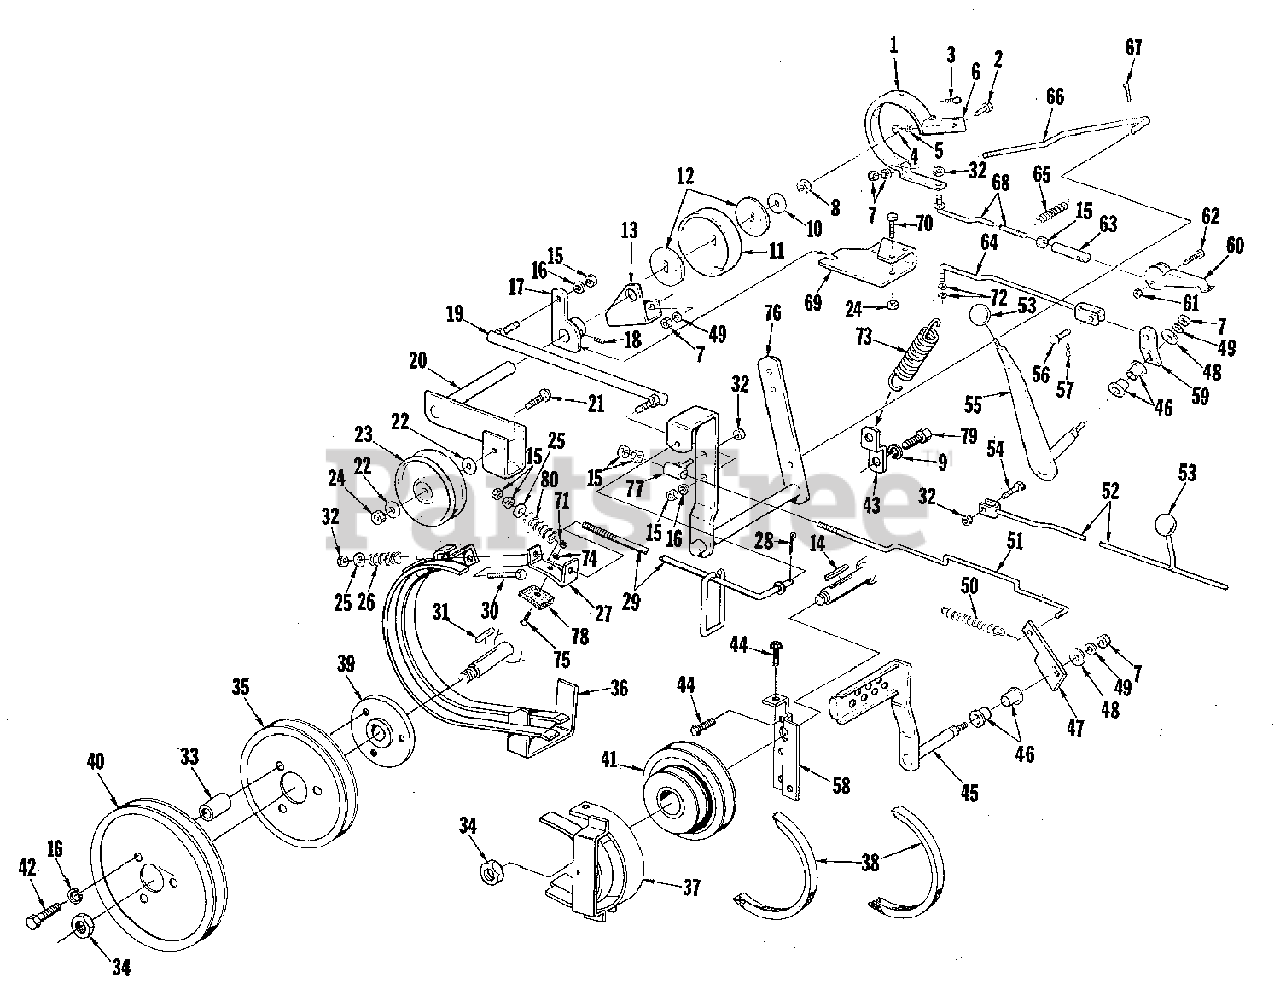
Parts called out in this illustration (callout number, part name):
1	BAND ASSEMBLY, Brake
2	SCREW, Hex Head Cap, 3/8-16 x 1-1/4
3	SCREW, Hex Head Cap, 1/4-20 x 3/4
4	NUT, Hex Fin, 1/4-20
5	WASHER, Lock, 1/4
6	BRACKET, Brake Hand
7	NUT, Hex Fin, 3/8-16
8	NUT, Lock, 7/16-14
9	WASHER, Lock
10	WASHER, Flat, 5/16
12	WASHER, Special
13	BEARING, Idler Pivot
14	KEY, Woodruff, #5
15	NUT, Hex Fin, 5/16-18
16	WASHER, Lock, 5/16
17	LEVER ASSEMBLY, Cam Shaft
18	SETSCREW, Hex Socket, 1/4-20 x 1/4
19	JOINT, Ball, Double End
20	ARM ASSEMBLY, Idler
21	CARRIAGE BOLT, 3/8-16 x 1
22	WASHER, Flat
24	NUT, Hex Lock, 3/8-16
25	WASHER, Flat
27	BRAKE, Sheave
29	ROD, Pulley Brake
30	SCREW, Hex Head Cap, 5/16-18 x 2-1/2
32	NUT, Hex Lock, 5/16-18
34	NUT, Lock Jam, 3/4-16
36	RETAINER ASSEMBLY, Rear
37	RETAINER ASSEMBLY, Belt
38	BELT, "V", Dual Range Drive
41	PULLEY, Front
42	SCREW, Hex 5/16-18 x 2
43	CLIP, Spring
44	SCREW, Hex Washer, 5/16-18 x 1/2
45	PEDAL ASSEMBLY, Foot
46	BUSHING, Flanged
47	ARM, Foot Pedal
49	WASHER, Lock, 3/8
50	SPRING, Brake Pedal
51	ROD, Clutch & Brake
52	ROD, Shift Assembly
53	BALL, Shift Lever
54	SCREW, Hex Head Cap
55	LEVER ASSEMBLY
58	SUPPORT, Belt Retainer
59	LINK, Speed Control
60	LEVER, Parking Brake
61	NUT, Hex Lock, 1/4-20
62	SCREW, Hex Head Cap, 1/4-20 x 1-1/4
64	ROD ASSEMBLY, Control
68	ROD ASSEMBLY, Parking Brake
70	SCREW, Hex Head Cap, 3/8-16 x 2
71	NUT, Hex, 10-24
72	RING, "E", External
73	SPRING, Tension
74	WASHER, Lock, #10
75	SCREW, Flat, 10-24 x 5/8
76	LEVER ASSEMBLY, Pivot
77	GUIDE ASSEMBLY, Rod
78	STRAP, Pulley Brake
79	SCREW, Hex Head Cap, 7/16-14 x 1-1/4
